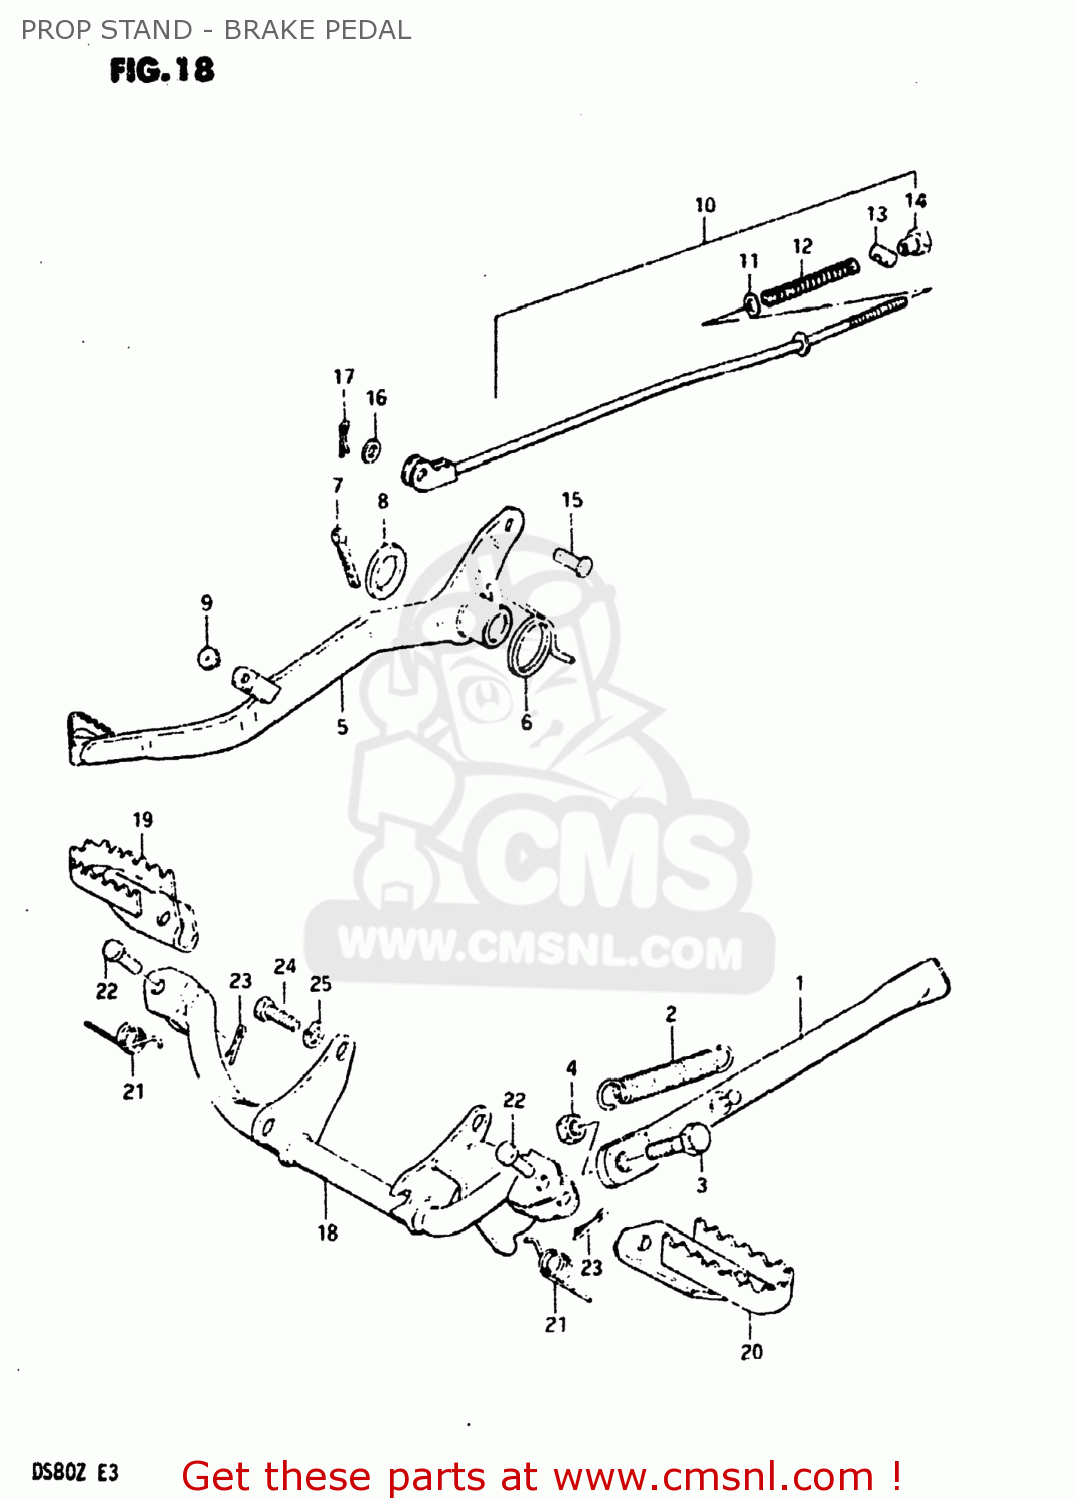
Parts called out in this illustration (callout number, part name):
1	STAND,SIDE
2	SPRING
3	BOLT
4	NUT
5	PEDAL,BRAKE
6	SPRING
7	COTTER PIN
8	WASHER(15.5X26X2.3)
9	STOPPER,BRAKE PEDAL
10	ROD ASSEMBLY,REAR BRAKE
11	WASHER
12	SPRING
13	PIN(11X18)
14	NUT
15	PIN(L:13.5)
16	WASHER
17	PIN 20X20
18	BAR,FRONT FOOTREST
19	FOOTREST,FRONT,RIGHT
20	FOOTREST
21	SPRING
22	PIN
23	PIN 20X20
24	BOLT
25	LOCK WASHER
